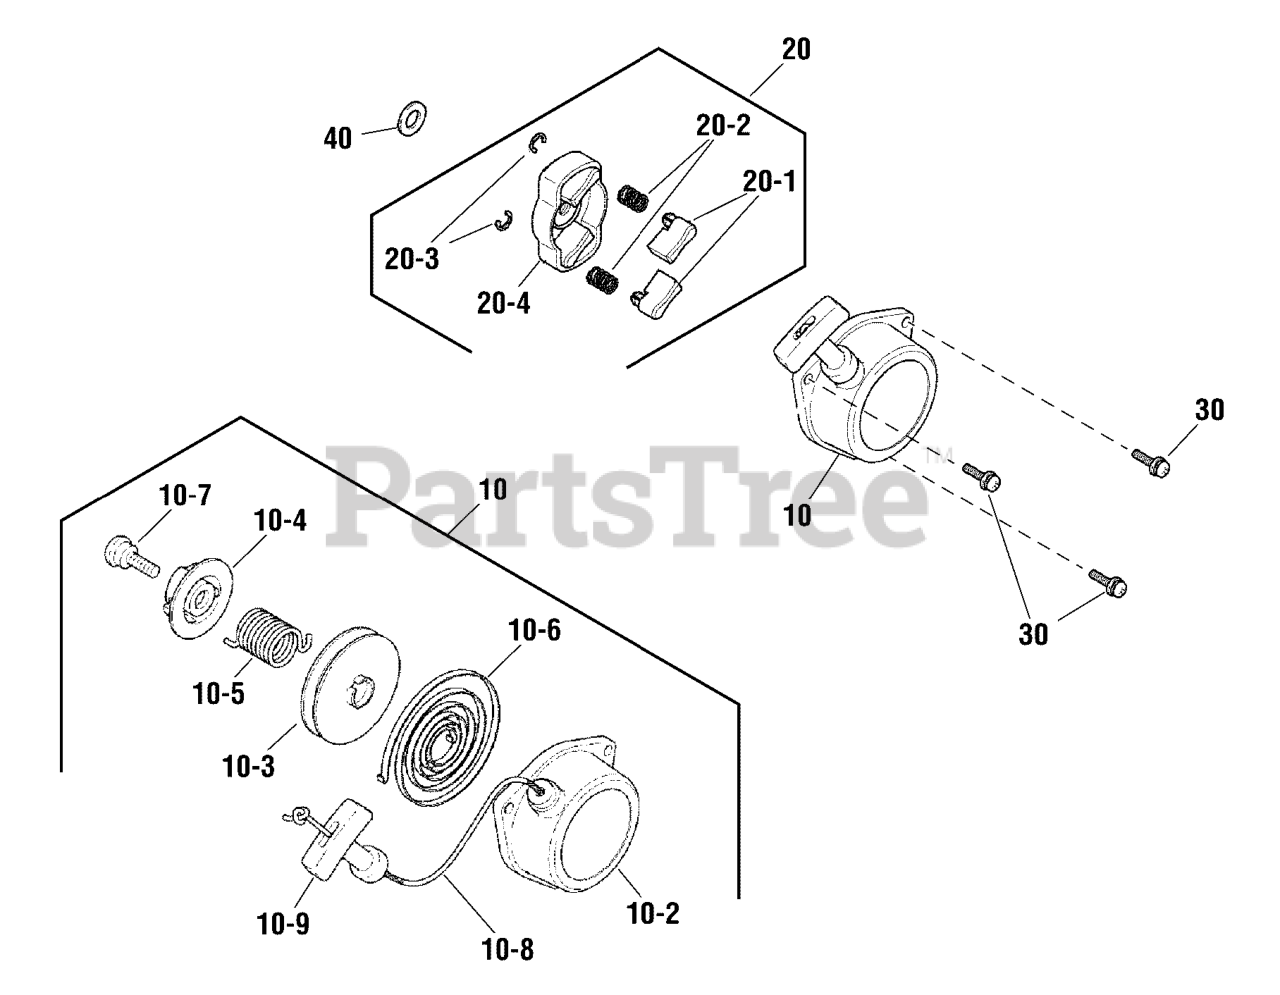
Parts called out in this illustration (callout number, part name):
10	RECOIL STARTER
10-2	CASE, Starter
10-3	REEL
10-4	CAM
10-5	SPRING
10-6	SPRING
10-7	SCREW
10-8	ROPE, Starter
10-9	KNOB, Starter
20	PULLEY, Starter
20-1	RATCHET
20-2	SPRING, Return
20-3	SNAP RING
20-4	STOPPER
30	SCREW & WASHER
40	WASHER
